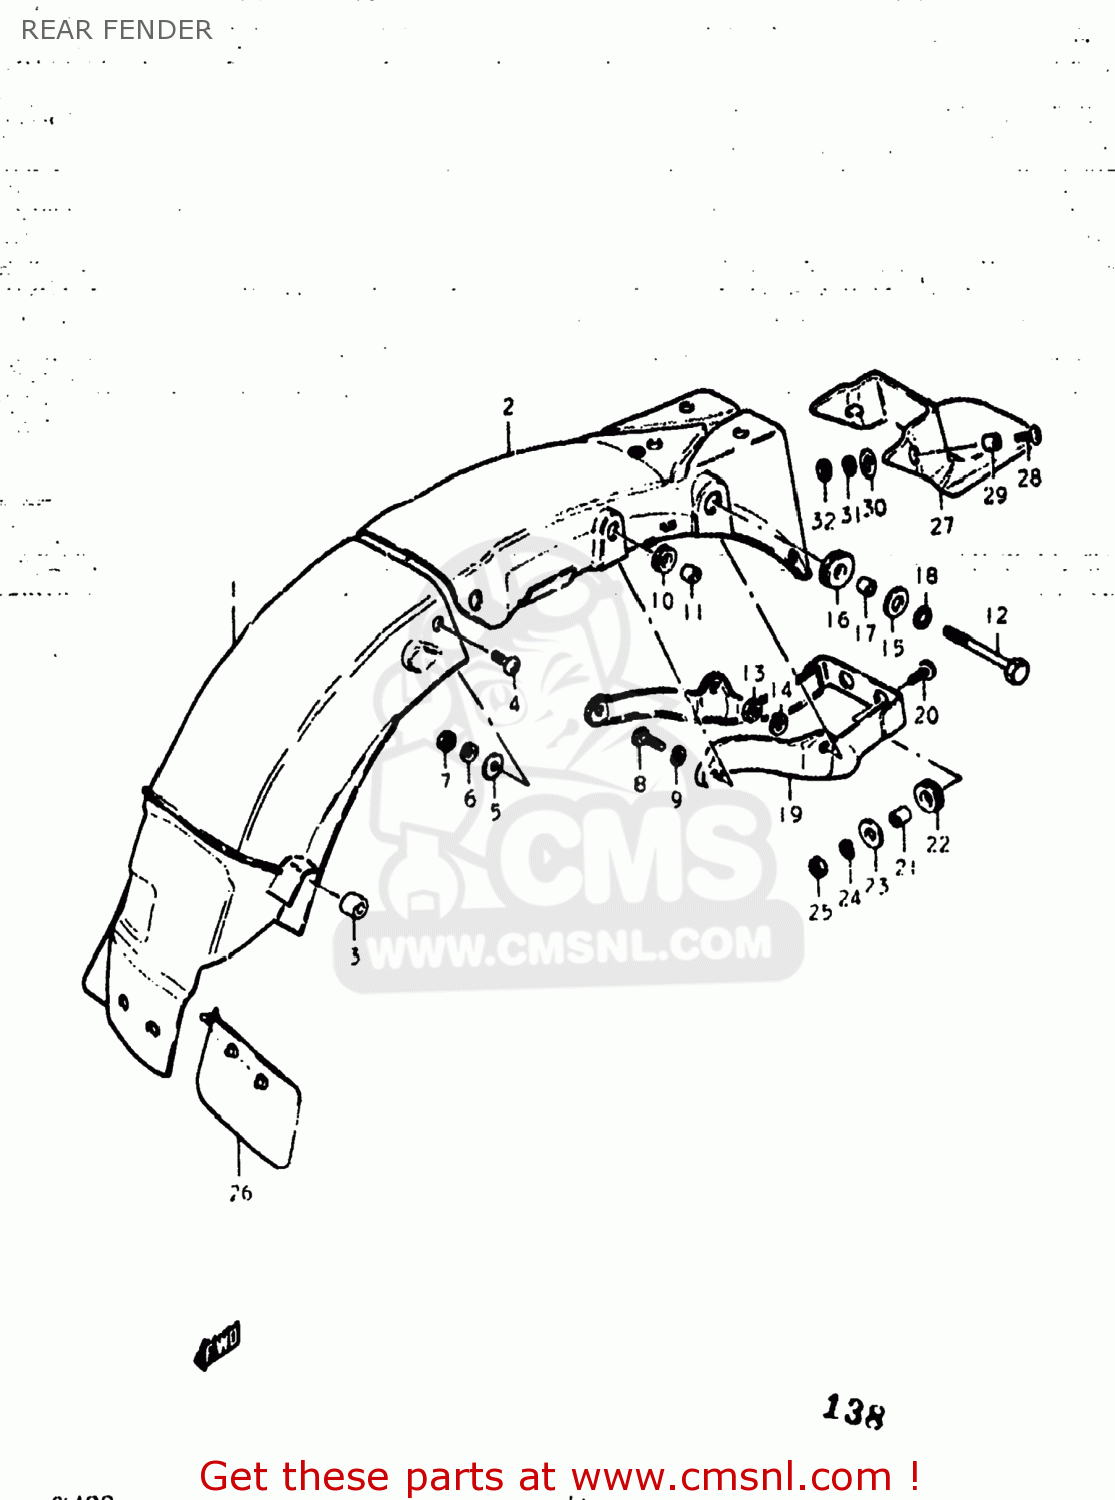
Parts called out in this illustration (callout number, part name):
1	FENDER,REAR
2	FENDER,REAR
3	CUSHION
4	SCREW
5	WASHER (5.5X16X1.2)
6	LOCK WASHER
7	NUT
8	BOLT
9	LOCK WASHER
10	CUSHION
11	SPACER(6.1X9X7.5)
12	BOLT
13	NUT
14	LOCK WASHER
15	WASHER(8.5X26X1.2)
16	CUSHION
17	SPACER (8.2X12X7.5)
18	WASHER
19	REINFORCEMENT,REAR FENDER
20	SCREW
21	SPACER (6.1X9X9)
22	CUSHION
23	WASHER(6,5X22X1.6)
24	LOCK WASHER
25	NUT
26	MUD GUARD,REAR FENDER
27	EXTENSION,REAR FENDER
28	SCREW (6X15)
29	SPACER(6.2X8.3X5.7)
30	WASHER(6.5X18X1)
31	LOCK WASHER
32	NUT
